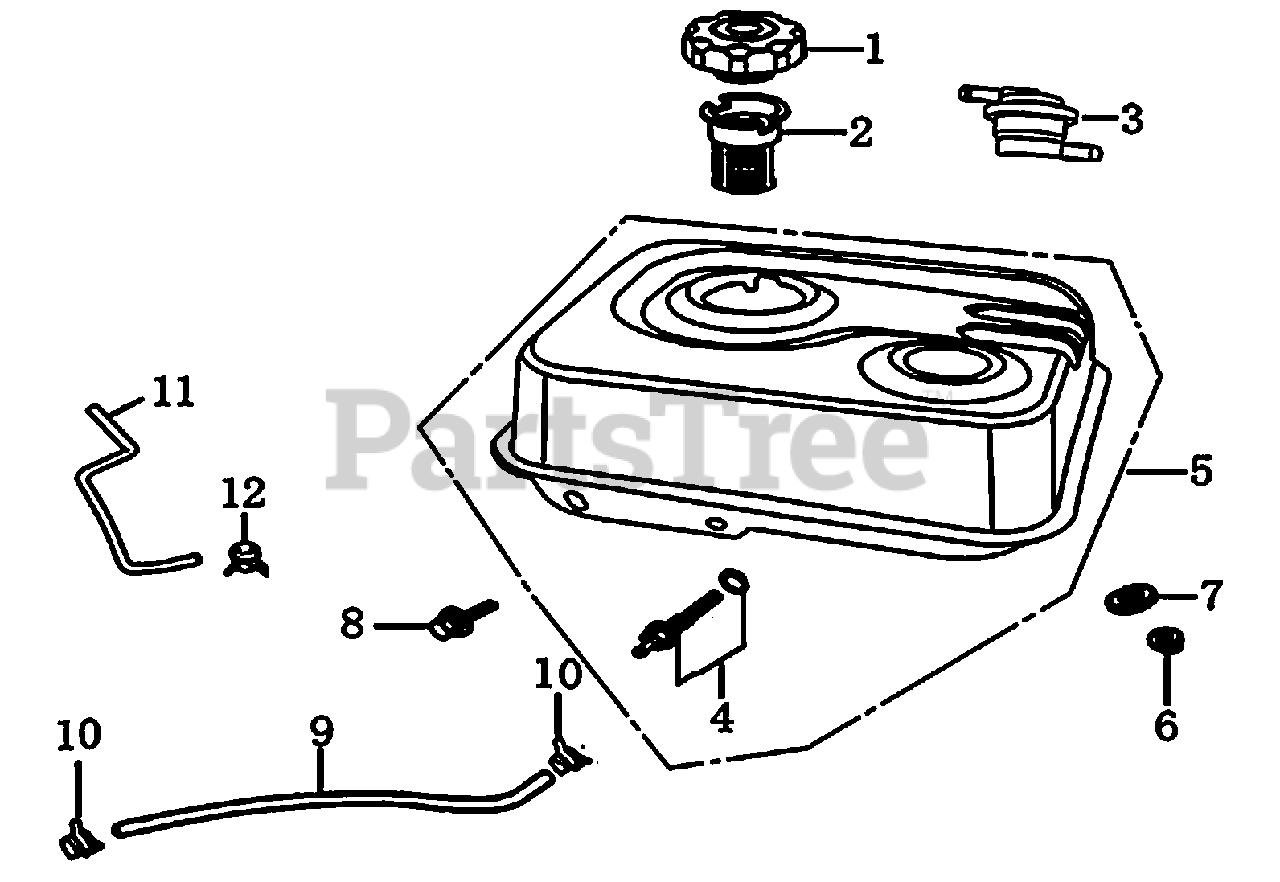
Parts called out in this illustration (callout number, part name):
1	CAP COMP., FUEL FILLER
2	FILTER, FUEL
3	VALVE, ROLL OVER
4	JOINT ASSY., FUEL TANK
5	TANK COMP., FUEL
6	NUT, FLANGE
7	WASHER, RUBBER
8	BOLT, FLANGE
9	TUBE, FUEL
10	CLAMP, HOSE
11	HOSE, ROLL OVER VLV, FORMED
12	CLAMP, HOSE
